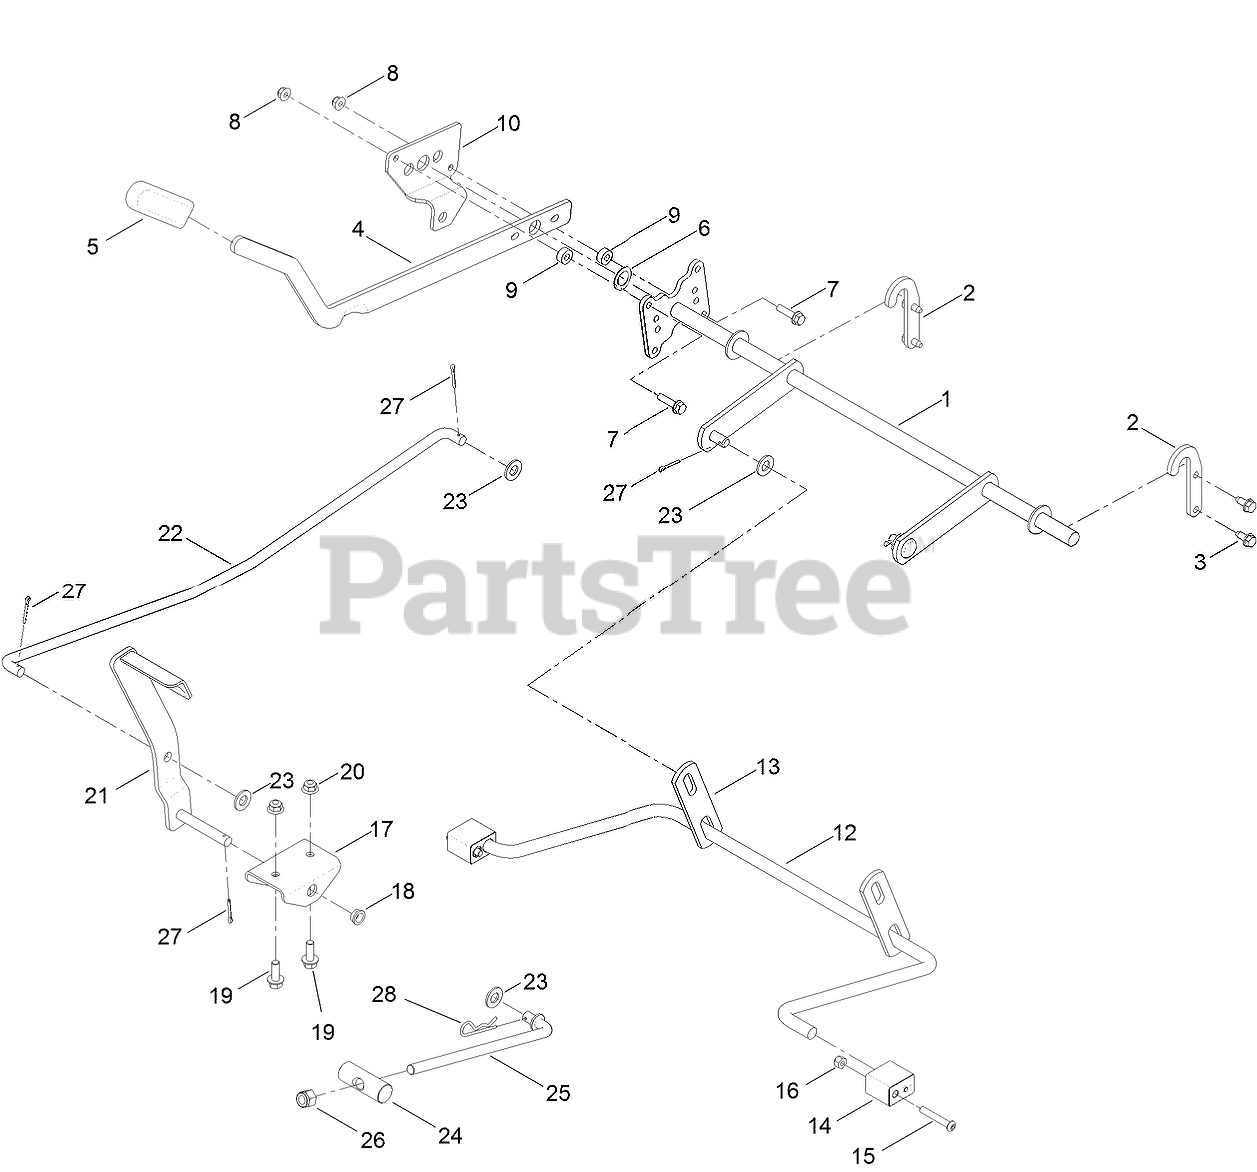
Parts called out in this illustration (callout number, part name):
1	LIFT-DECK, WIDE
2	BRACKET-LIFT
3	SCREW-HWHTF
4	LEVER-LIFT
5	GRIP-LEVER
6	WASHER-THRUST
7	SCREW-HHF
8	NUT-HF, NI
9	SPACER
10	PLATE-FOOTLIFT
12	ARM-LIFT, REAR (WIDE)
13	LINK-LIFT
14	BLOCK-PIVOT
15	SCREW-HSBH
16	NUT-LOCK, NI
17	BRACKET-FOOTLIFT
18	BUSHING-FLANGE
19	SCREW-HHF
20	NUT-HF, NI
21	PEDAL ASM
22	ROD-FOOTLIFT
23	WASHER-FLAT
24	PIN-PIVOT
25	ROD-MOUNT, DECK
26	NUT-HEX
27	PIN-COTTER
28	PIN-COTTER
